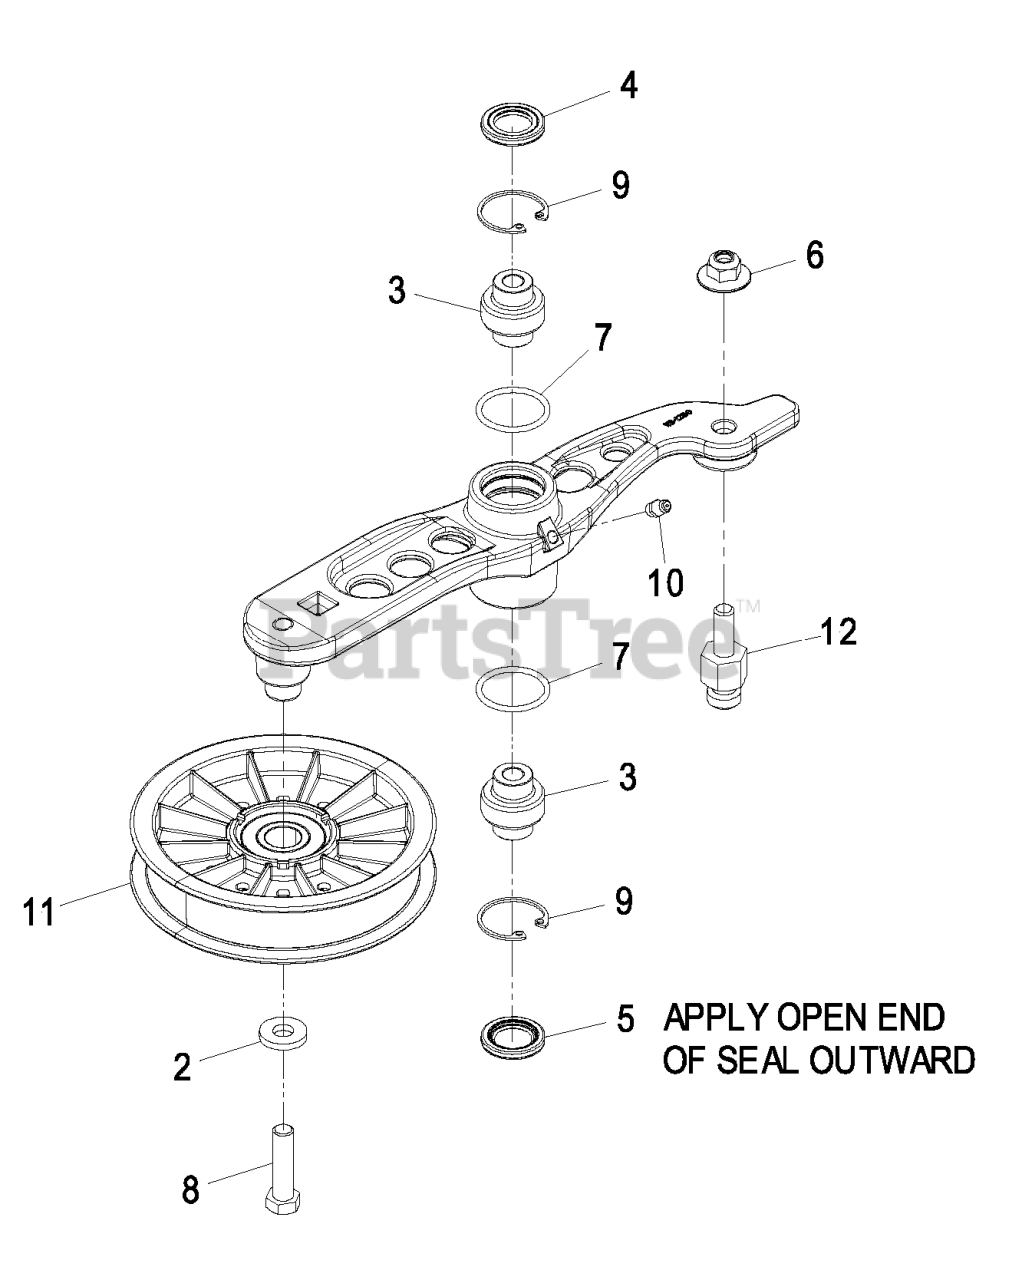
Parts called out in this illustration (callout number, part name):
3	BEARING-SPHERICAL
4	SEAL-LIP, DOUBLE
5	SEAL-LIP, SINGLE
6	Nut-Nyloc 3/8-16 Flg
8	SCREW-HH
9	RING-SNAP
10	FITTING-GREASE
11	PULLEY-IDLER
